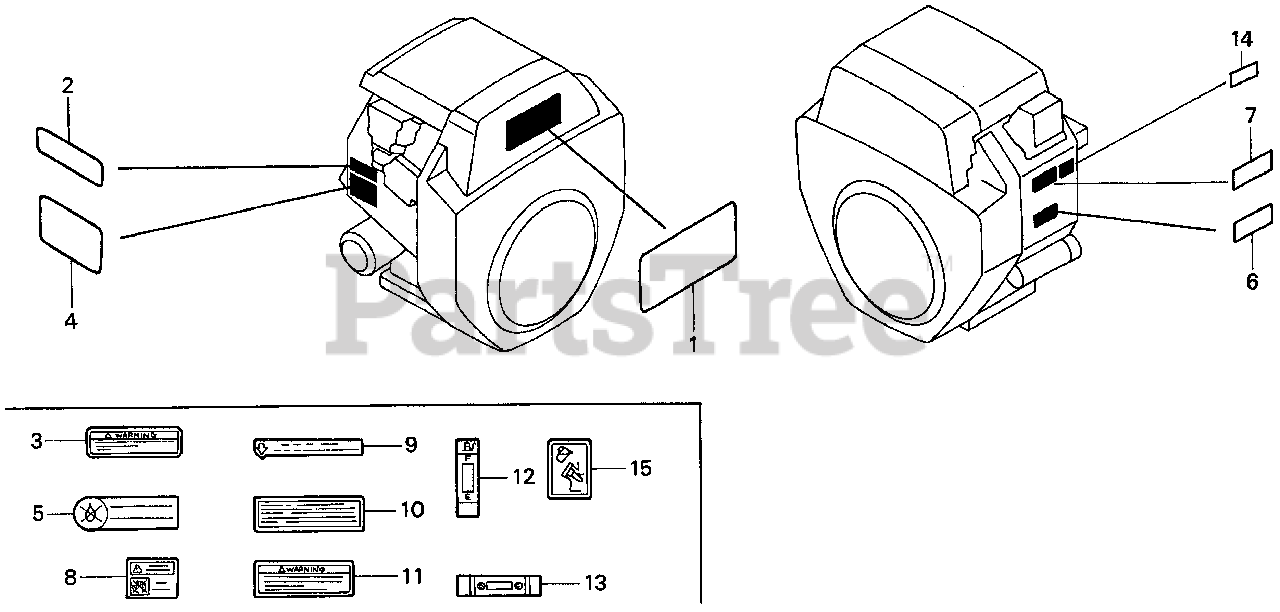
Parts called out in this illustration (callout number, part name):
1	MARK, EMBLEM (GX620)
2	LABEL, SPECIFICATION (GX620)
4	LABEL, CAUTION
